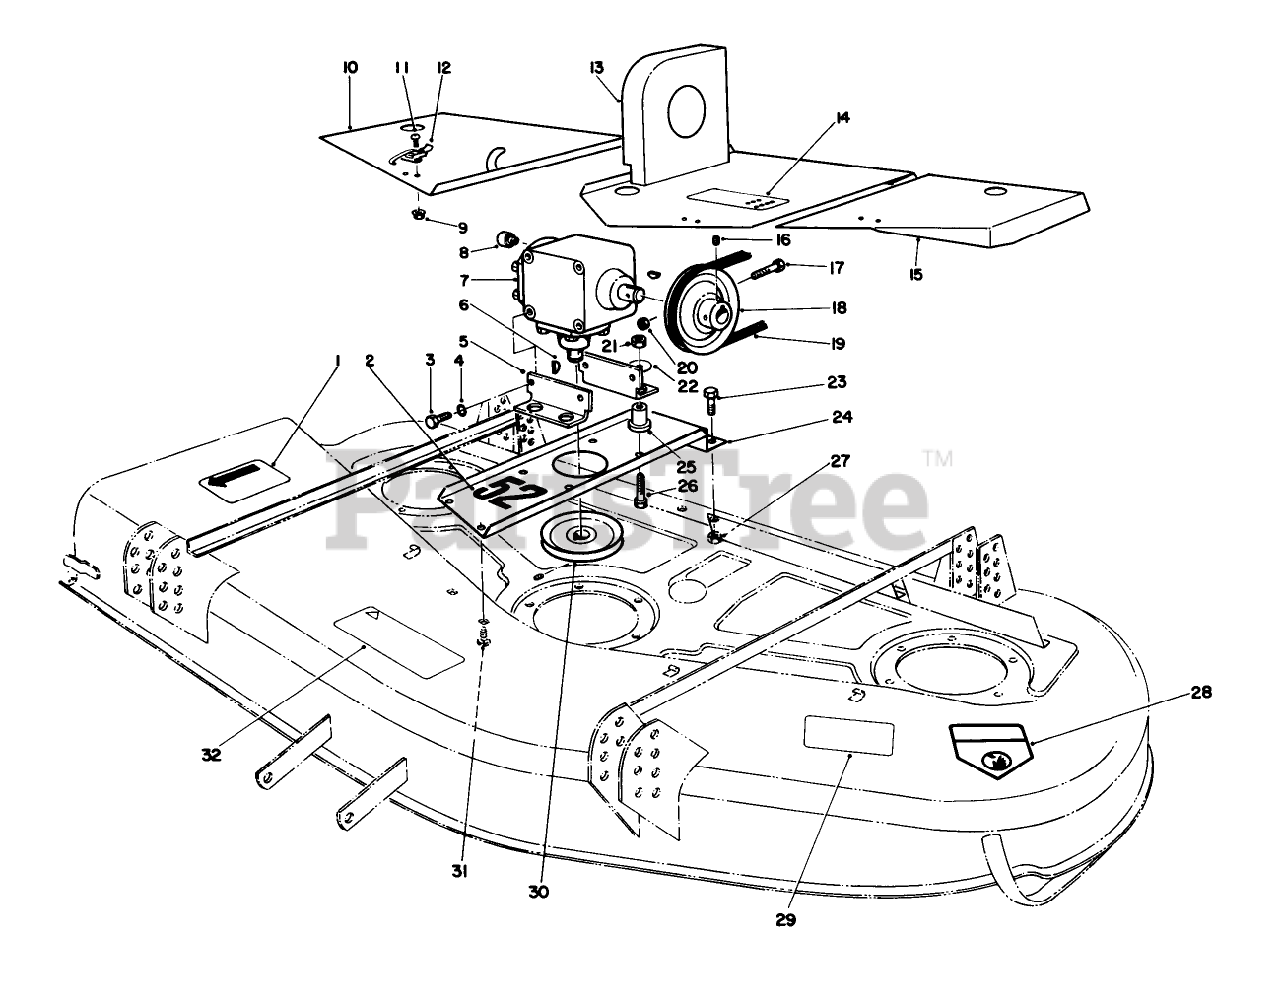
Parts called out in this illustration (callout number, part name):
2	DECAL
3	SCREW-HH
4	WASHER-LOCK
8	FITTING-LUBE
9	NUT-LOCK, FLANGE
11	SCREW-HWH
12	CLAMP-SLOTTED
16	SCREW-SET, SQH
17	SCREW-HH
18	PULLEY
19	V-BELT, DECK
20	NUT-LOCK, NI
21	NUT-LOCK, SIDE
22	WASHER
23	SCREW-HH
25	MOUNT
26	SCREW-HH
27	NUT-LOCK, NI
28	DECAL-DANGER
30	PULLEY
31	BOLT-CARR
